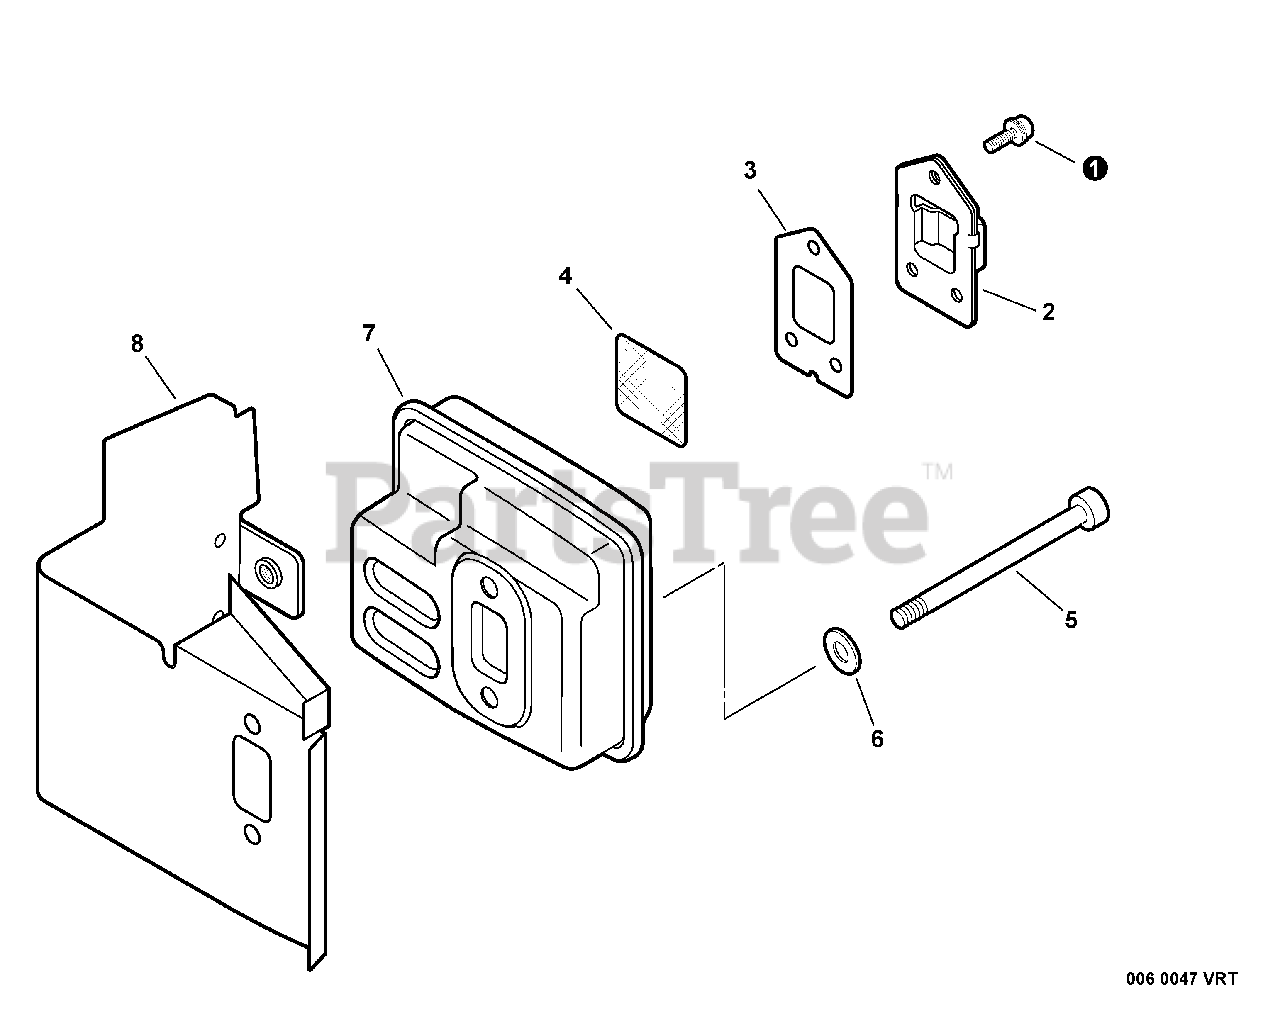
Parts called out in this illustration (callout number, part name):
1	SCREW 4×10
2	GUIDE, EXHAUST
3	GASKET, EXHAUST
4	SCREEN, SPARK ARRESTER
5	BOLT M5×50
6	WASHER, FLAT 5.5×10×0.8
8	HEAT SHIELD, EXHAUST
